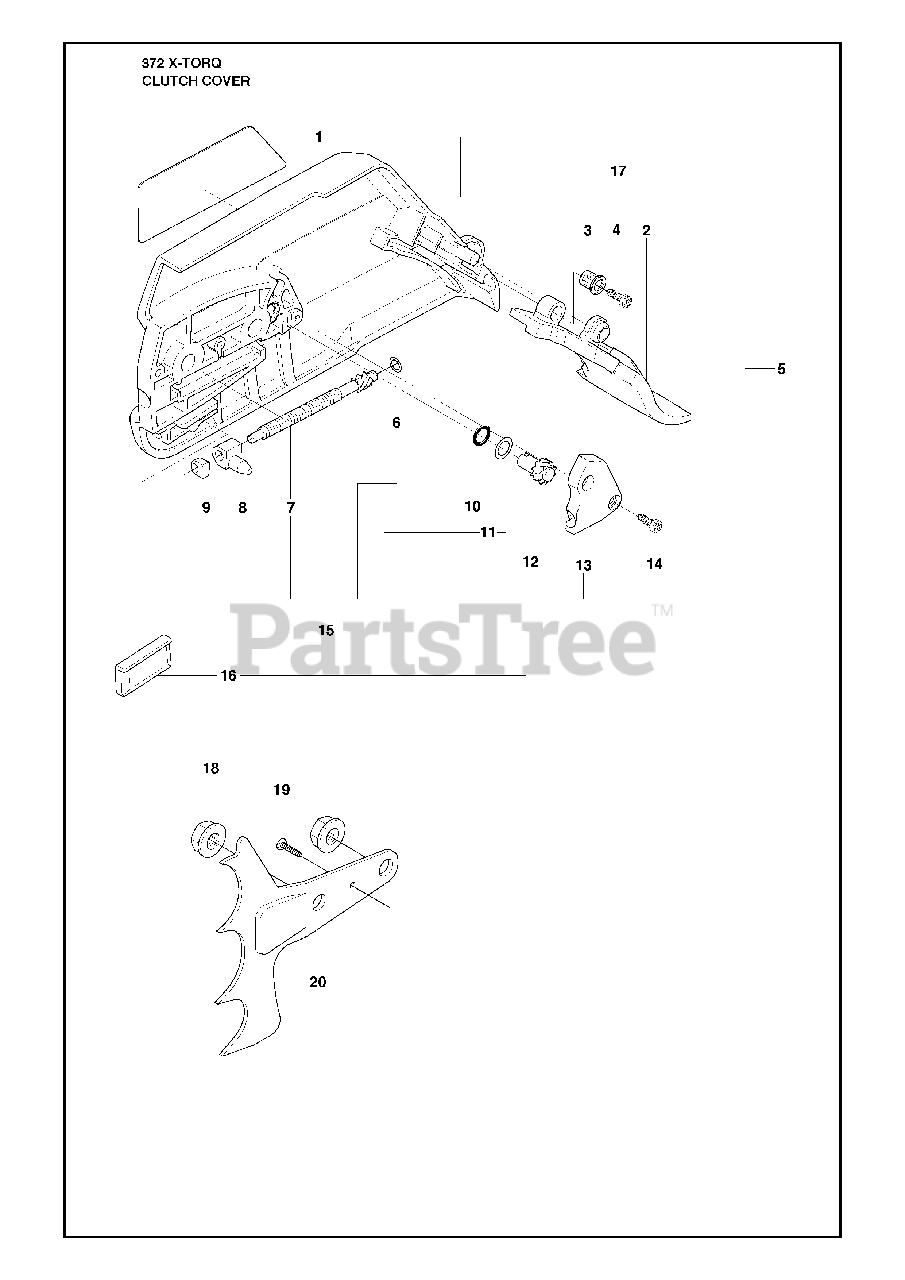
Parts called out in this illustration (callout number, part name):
5	CHAIN BRAKE COVER
7	ADJUSTER
12	RP ADJUSTER
15	KIT-CHAIN TENSIONER
16	CHAIN GUIDE
17	CHAIN BRAKE COVER
18	NUT M8 FLANGE
20	SPIKE OUTER
